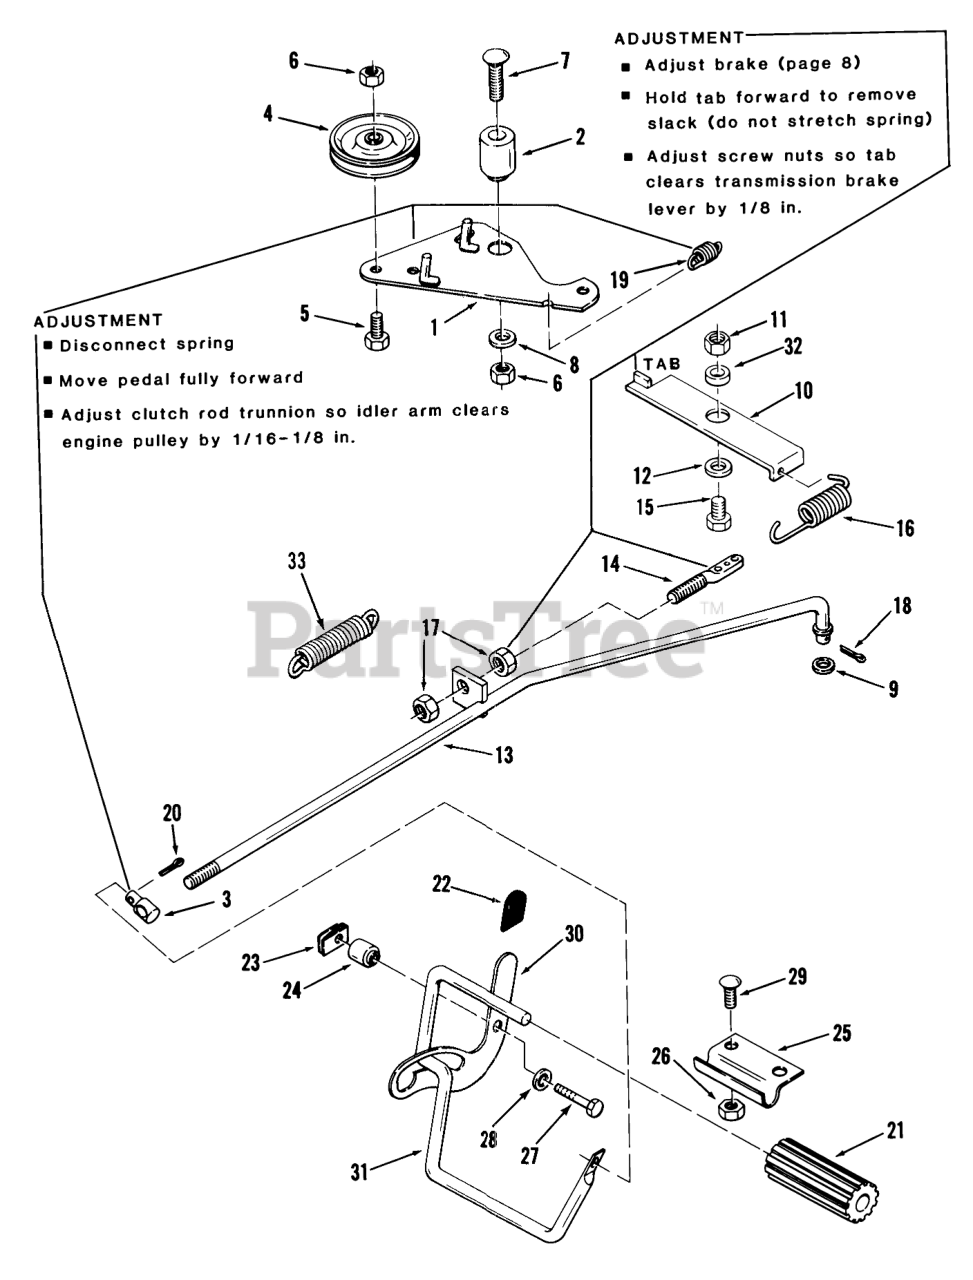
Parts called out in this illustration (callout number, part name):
1	ASSY-IDLER ARM
2	SPACER-CLUTCH ARM
3	TRUNNION
4	PULLEY-IDLER STATION
5	BOLT
6	Nut
7	Bolt
8	WASHER
9	Washer
10	Brake Rod
11	Nut
12	WASHER 5/16 SAE
13	Clutch Rod
14	Screw Adjustment
15	Bolt
16	Spring
17	Nut
18	Cotter Pin
19	SPRING
20	Cotter Pin
21	PAD-CLUTCH/BRKE PDL
22	GRIP
24	Spacer-Park Brake Lever
25	SPINDAL SUPPORT R
26	Nut
27	Bolt 1/4-20 X 1 1/2
29	Bolt-Carriage
30	Park Brake Lever
31	ROD-PEDAL
32	SPACER
33	SPRING-EXTENSION
